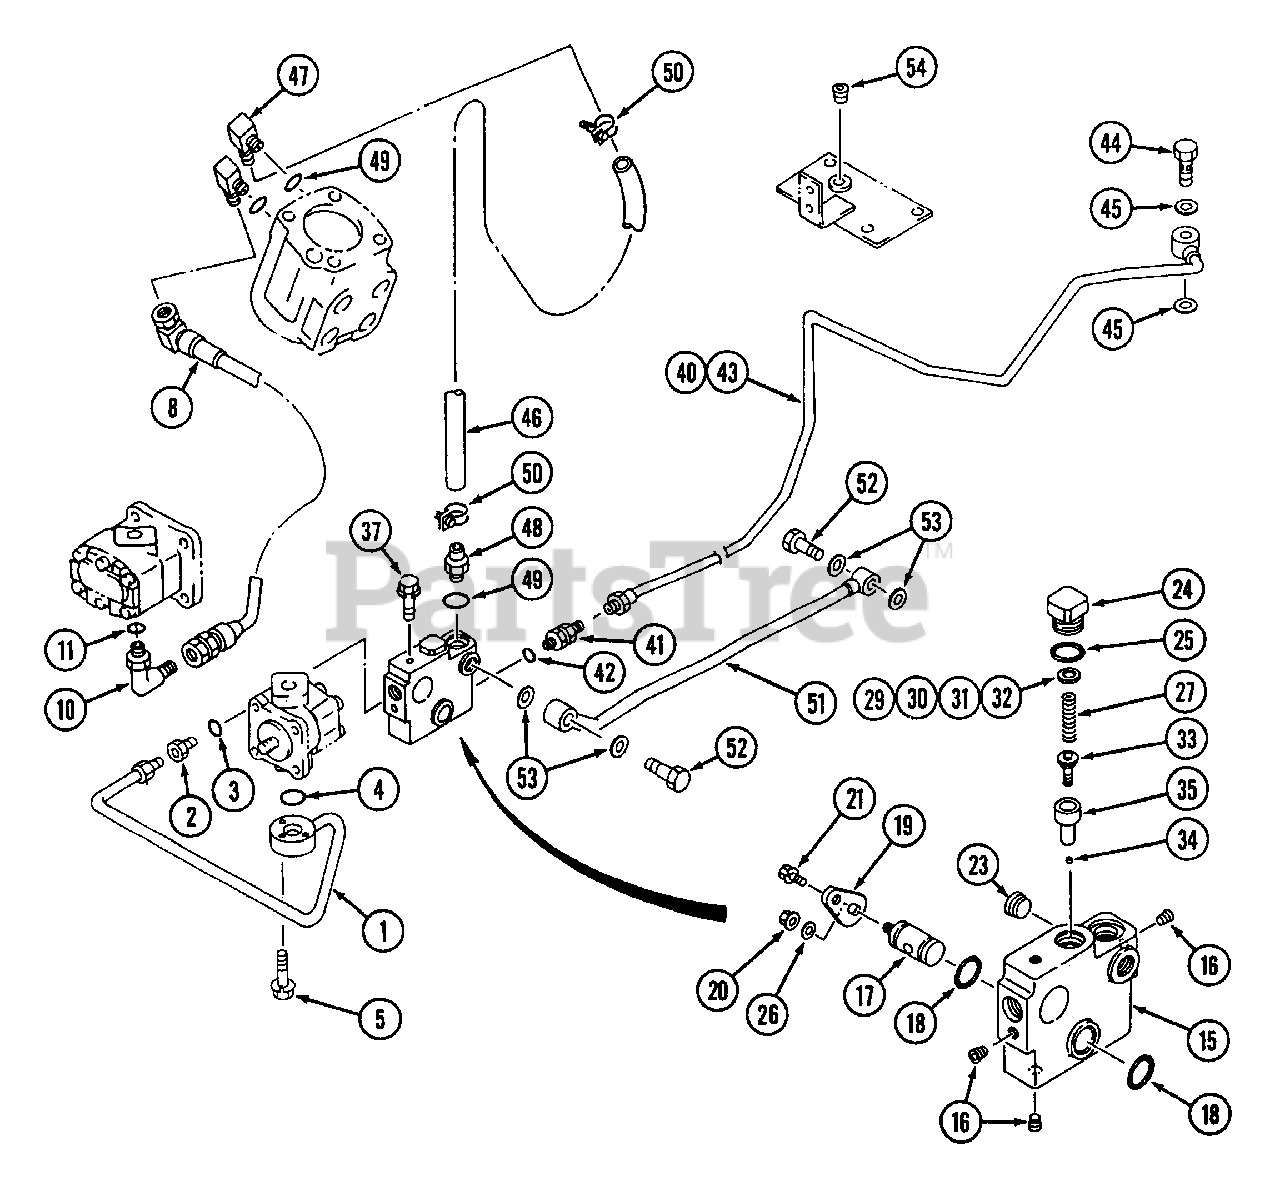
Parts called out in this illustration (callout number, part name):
1	Pipe, A Pre Ass'y.
2	Body (Nipple)
10	Body
34	Ball
35	Relief, Housing (NLA)
40	Pipe, C Pre Ass'y.
41	Body (Nipple)
43	Pipe, D Pre Ass'y.
45	Seal Washer
47	Adapter
48	Adapter
53	Seal, Washer
